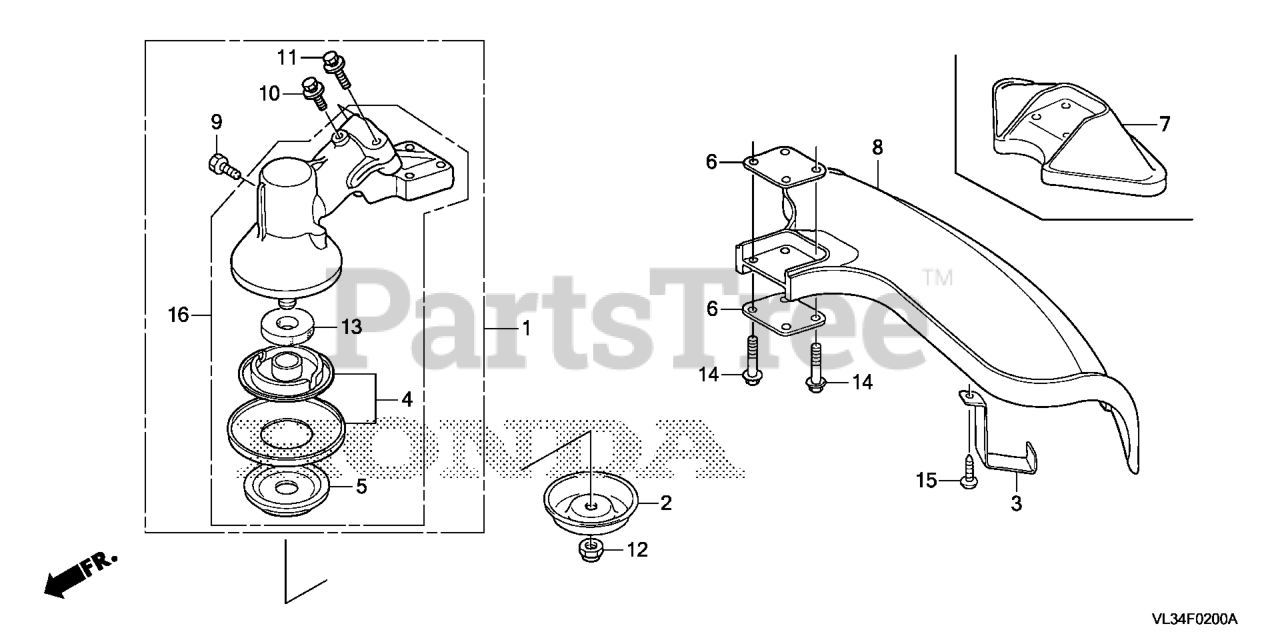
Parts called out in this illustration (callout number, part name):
2	COVER, NUT
3	PLATE, NYLON CUTTING
4	HOLDER, BLADE
5	HOLDER B, BLADE
6	SPACER, DEFLECTOR
7	DEFLECTOR, GRASS
8	DEFLECTOR, GRASS
9	BOLT, HEX. (8X10)
10	SCREW-WASHER (5X12)
11	BOLT-WASHER (5X25)
12	NUT, LOCK (10MM)
14	BOLT-WASHER (5X28)
15	SCREW, TAPPING (5X12) (PO)
16	CASE ASSY., GEAR
